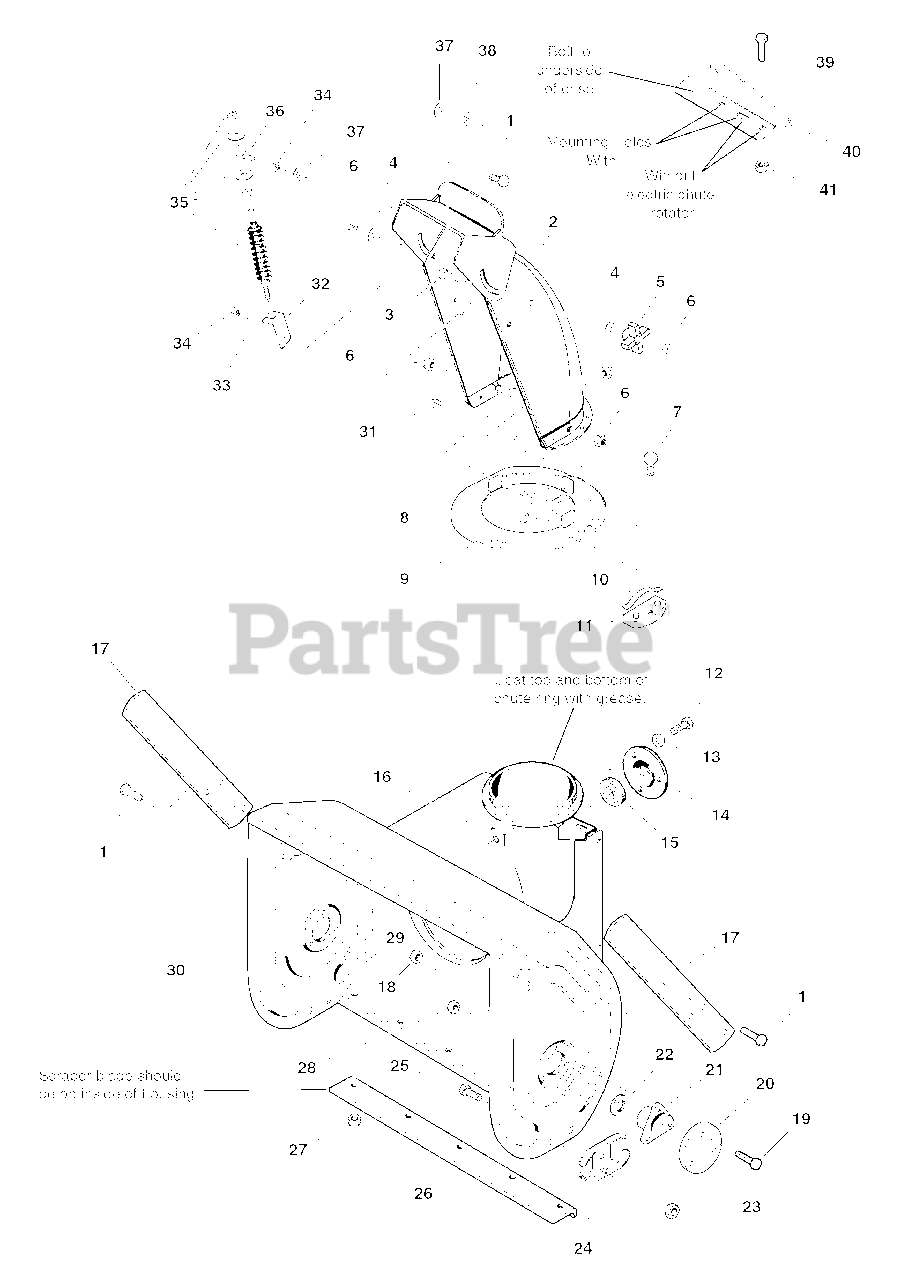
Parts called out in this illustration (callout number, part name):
1	CAPSCREW, Hex Head, 5/16-18 x 3/4 G5
2	CHUTE AND DEFLECTOR ASSEMBLY, w/Remote
2	CHUTE AND DEFLECTOR ASSEMBLY, Manual
3	BOLT, Carriage, Short Neck, 5/16-18 x 1
4	WASHER, 5/16
5	KNOB, Internal Thread, 5/16
6	NUT, Hex Lock ESNA Light, 5/16-18
7	SCREW, Hex Washer Head Pastite, 10-14 x 5/8
8	RING AND TABS ASSEMBLY, Gear
9	CARRIAGE BOLT, 5/16-18 x 3/4
10	SPRING, Flat
11	HOLD DOWN, Chute
12	CAPSCREW, Hex Head, 5/16-18 x 5/8 G5
13	LOCKWASHER, Spring, 5/16
14	RETAINER, Bearing
15	BEARING, Ball
16	NUT, Retainer Speed, 5/16-18
17	CUTTER, Drift, 1/4" Thick, 20LG
18	NUT, Hex Keps Conical Washer, 5/16-18
19	CAPSCREW, Hex Head 5/16-18 x 7/8 G5
20	CAP, Bearing, 3-3/4OD
21	BEARING, Flange
22	SPACER, Low
23	NUT, Hex Flange 3/8-16 ESNA
24	SKID SHOE, Reversible
25	CARRIAGE BOLT, 3/8-16 x 3/4 G5
26	BLADE, Scraper, 24"
26	BLADE, Scraper, 28"
26	BLADE, Scraper, 32"
27	NUT, Hex Flange, 5/16-18, Two-Way Lock GA
28	NUT, Hex Centerlock, 5/16-18
29	CARRIAGE BOLT, 5/16-18 x 5/8 G5
30	HOUSING AND IMPELLER ASSEMBLY, 24", Red
30	HOUSING AND IMPELLER ASSEMBLY, 28"
30	HOUSING AND IMPELLER ASSEMBLY, 32", Red
31	CARRIAGE BOLT, 1/4-20 x 1/2 G5
32	MOUNT, Cable (See Only 986719)
33	LOCKWASHER, External Tooth, 1/4
34	NUT, Hex, 1/4-20 NC-2B
35	CABLE, Remote Chute Deflector, 60"
36	EYEBOLT, 1/4-20 x 1-1/2 LG
37	WASHER, 1/4
38	NUT, Hex Lock ESNA Light, 1/4-20NC-3B
39	CAPSCREW, Hex Head 1/4-20 x 3/4 G5
40	SUPPORT, Cable Tubular Handles, 12GA
41	NUT, Hex KEPS, 1/4-20, Conical Washer
